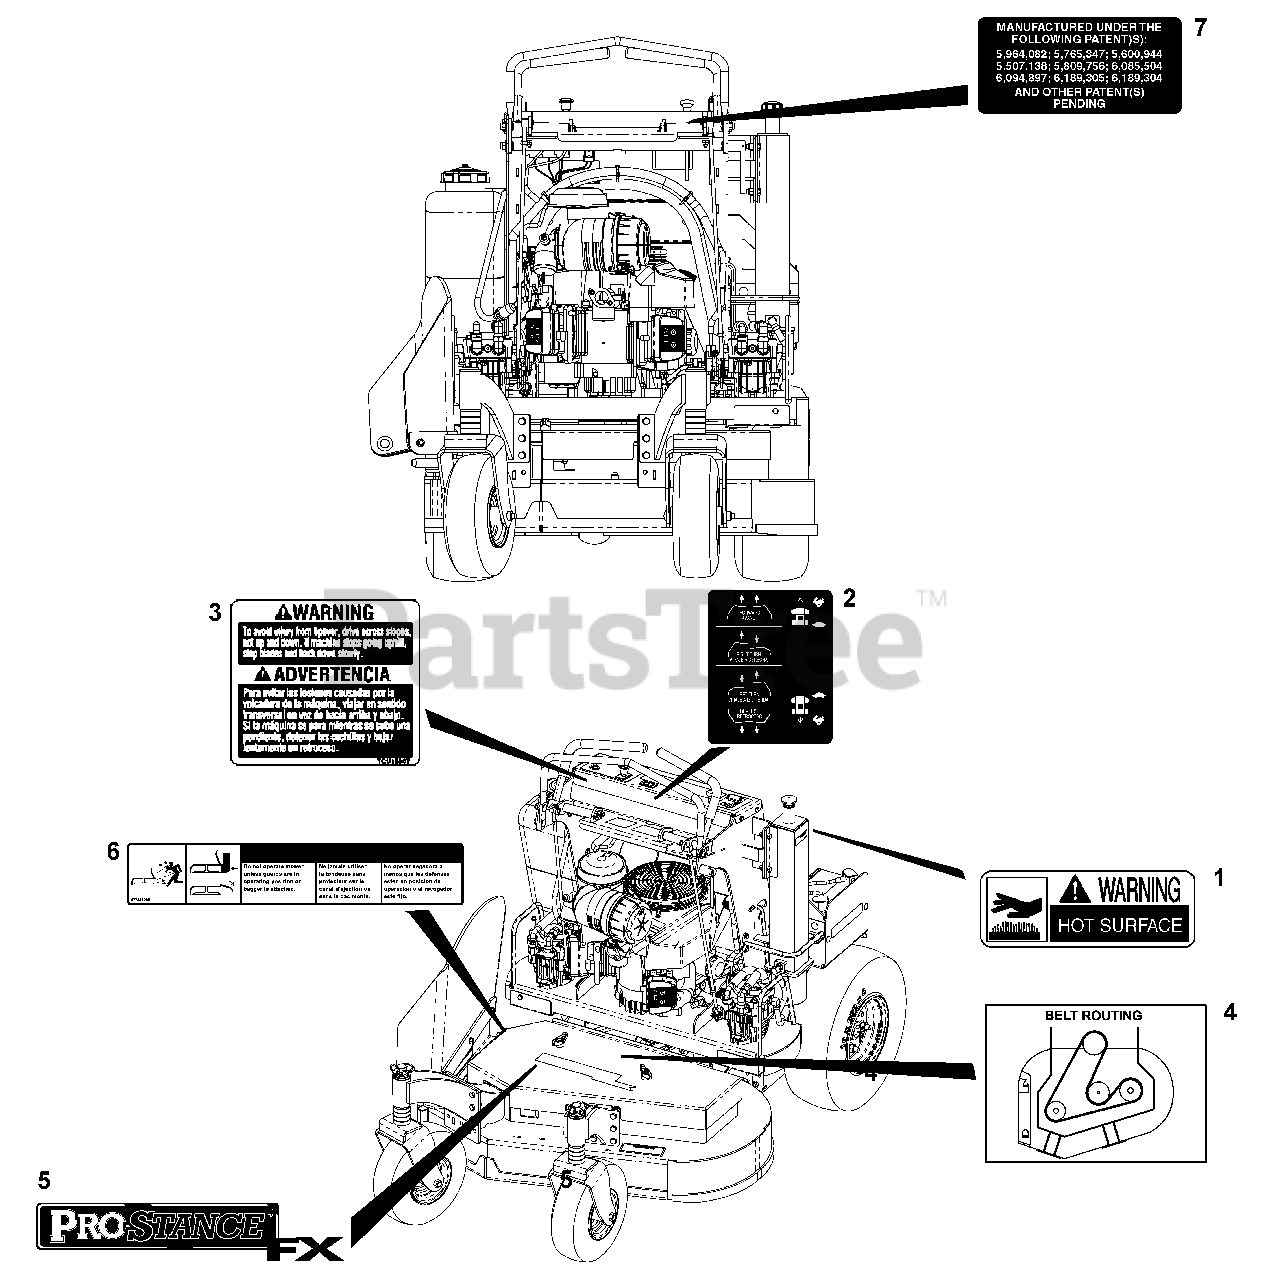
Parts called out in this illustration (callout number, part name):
1	Decal, Warning, Hot Surface
2	Decal, Directional Control
3	Decal, Danger - Avoid Tipover
4	Decal, Belt Path
5	Decal, Pro-Stance
6	Decal, Danger - Thrown Objects
7	Decal, Patent
